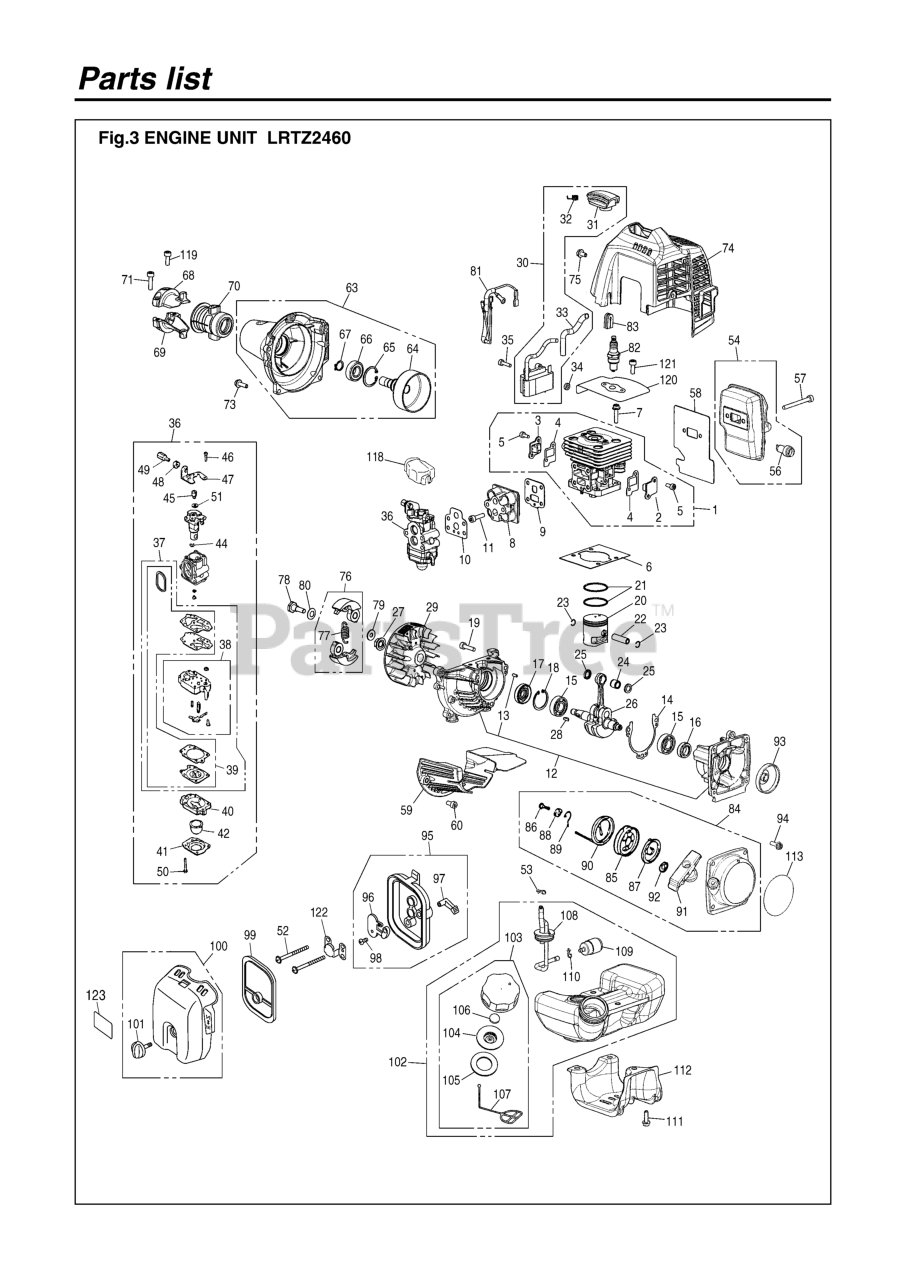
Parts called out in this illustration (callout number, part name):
1	CYLINDER COMP
2	COVER, TR-S
3	COVER, TR-F
4	GASKET, TR
5	BOLT
6	GASKET, BASE
7	BOLT
8	INSULATOR
9	INSULATOR GASKET
10	GASKET, CARB
11	BOLT, TORX
12	CRANKCASE-C
14	GASKET, CASE
15	BEARING MAIN
16	SEAL
17	SEAL, OIL (RPLS
19	BOLT (RPLS 28501
21	RING, PISTON
22	PIN, PISTON
23	RING, SNAP (RPLS
25	WASHER
26	CRANKSHAFT-C
27	NUT (RPLS 1140-4
28	KEY
30	COIL ASSY
31	CAP(RPLS 4810721
35	BOLT TORX
36	CARBURETOR ASSY
37	REBUILD KIT
38	BODY, PUMP
39	GASKET KIT
40	BODY, PURGE
41	COVER, PUMP
42	PUMP, PRIMING
49	SCREW
50	SCREW
51	WASHER
52	BOLT TORX
53	CLIP
56	ARRESTER
57	BOLT
58	GASKET, MUFFLER
60	BOLT
63	COVER, C
64	DRUM (RPLS 48103
68	BRACKET (A) (RPL
69	BRACKET (B)
70	CUSHION (RPLS T1
71	BOLT (RPLS 28501
73	BOLT
74	COVER, ENGINE
75	BOLT (RPLS T4950
76	SHOE COMP
77	SPRING
78	BOLT
79	WASHER
80	WASHER (RPLS 114
81	CORD COMP.
82	SPARKPLUG
83	GROMMET
84	RECOIL-A
85	REEL
86	SCREW
87	SPRING, SPIRAL
88	COLLAR
89	ARM
90	ROPE (RPLS 45007
91	KNOB (RPLS 3330-
92	PLATE, STOPPER
93	PULLEY
94	BOLT, TORX
95	CLEANER BODY ASS
96	PLATE, CHOKE
98	SCREW
99	ELEMENT
100	COVER ASSY
101	CLEANER KNOB
102	TANK ASSY
103	CAP ASSY
104	HOLDER (RPLS 450
105	PACKING
106	FILTER
107	STOPPER
108	PIPE-C
109	FILTER
110	CLIP (RPLS 28413
111	BOLT
112	GUARD, TANK
113	LABEL, RECOIL
118	COVER
119	BOLT
121	BOLT
